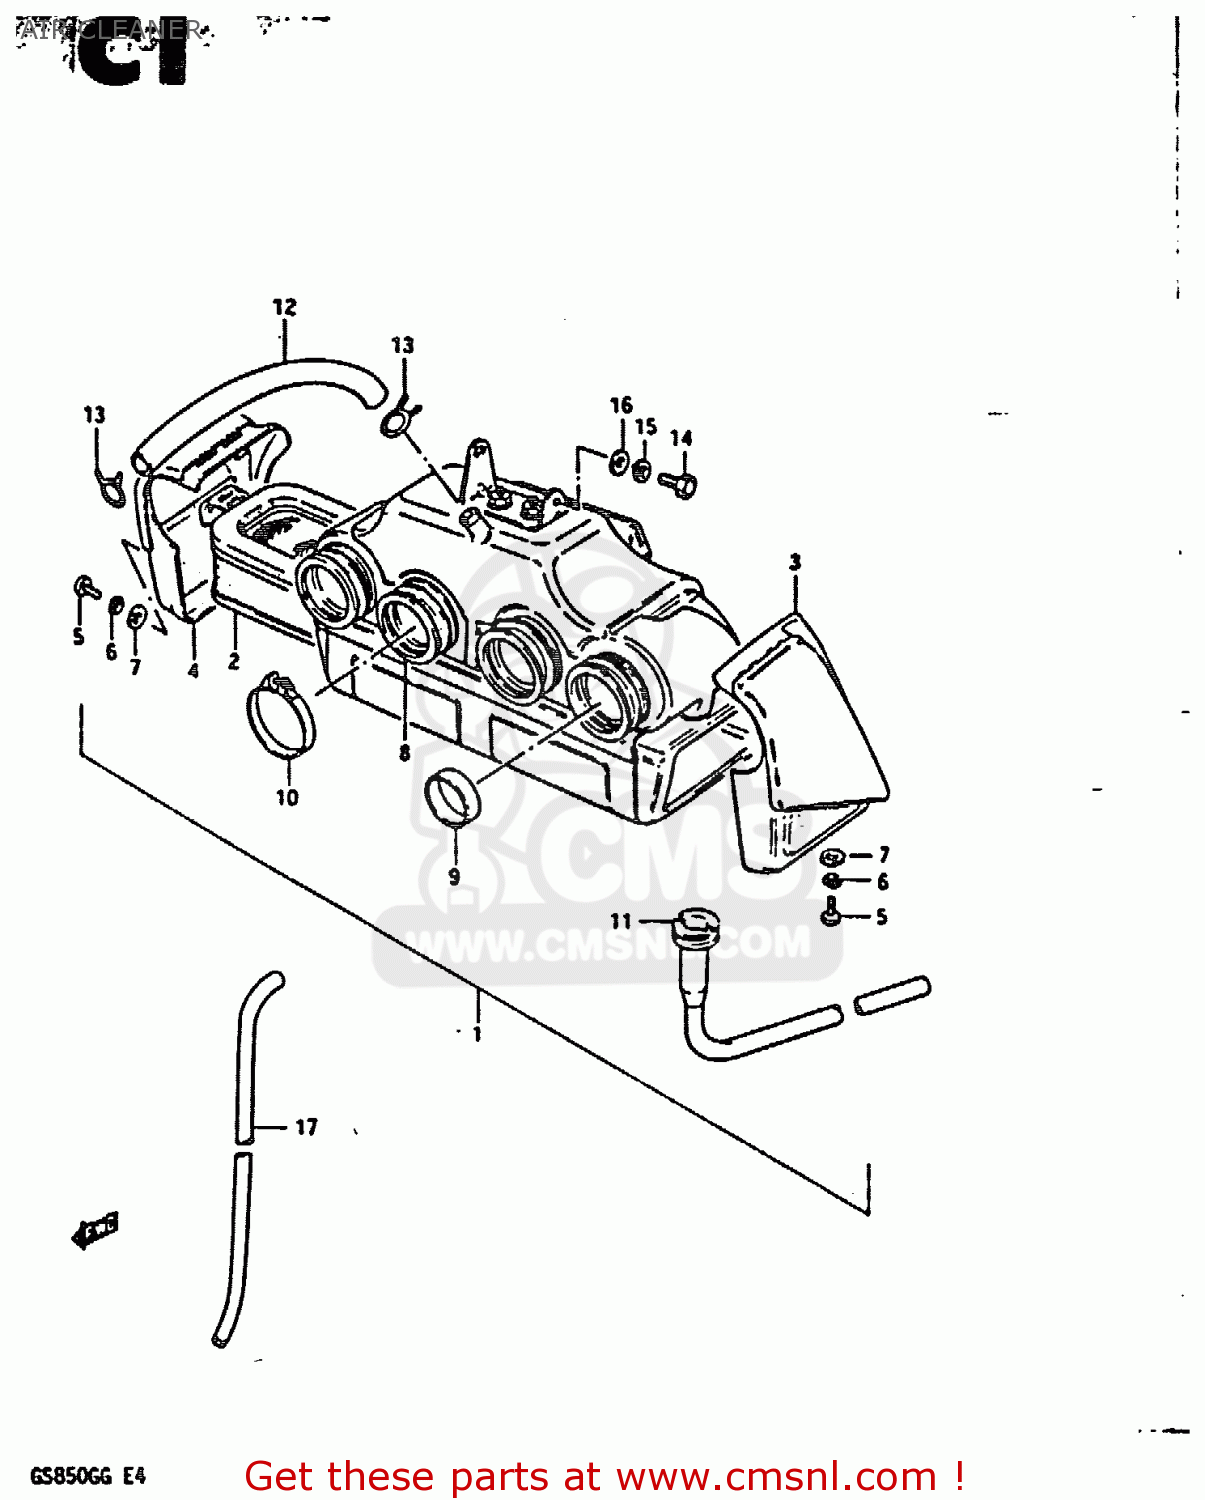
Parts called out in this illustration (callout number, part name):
1	CLEANER ASSEMBLY,AIR
2	FILTER ASSY
3	CAP,AIR CLEANER
4	CAP,AIR CLEANER
5	SCREW
6	LOCK WASHER
7	WASHER
8	TUBE,OUTLET
9	RING
10	CLAMP
11	DRAIN TUBE
12	TUBE,BREATHER
13	CLIP
14	BOLT
15	LOCK WASHER
16	WASHER
17	HOSE
